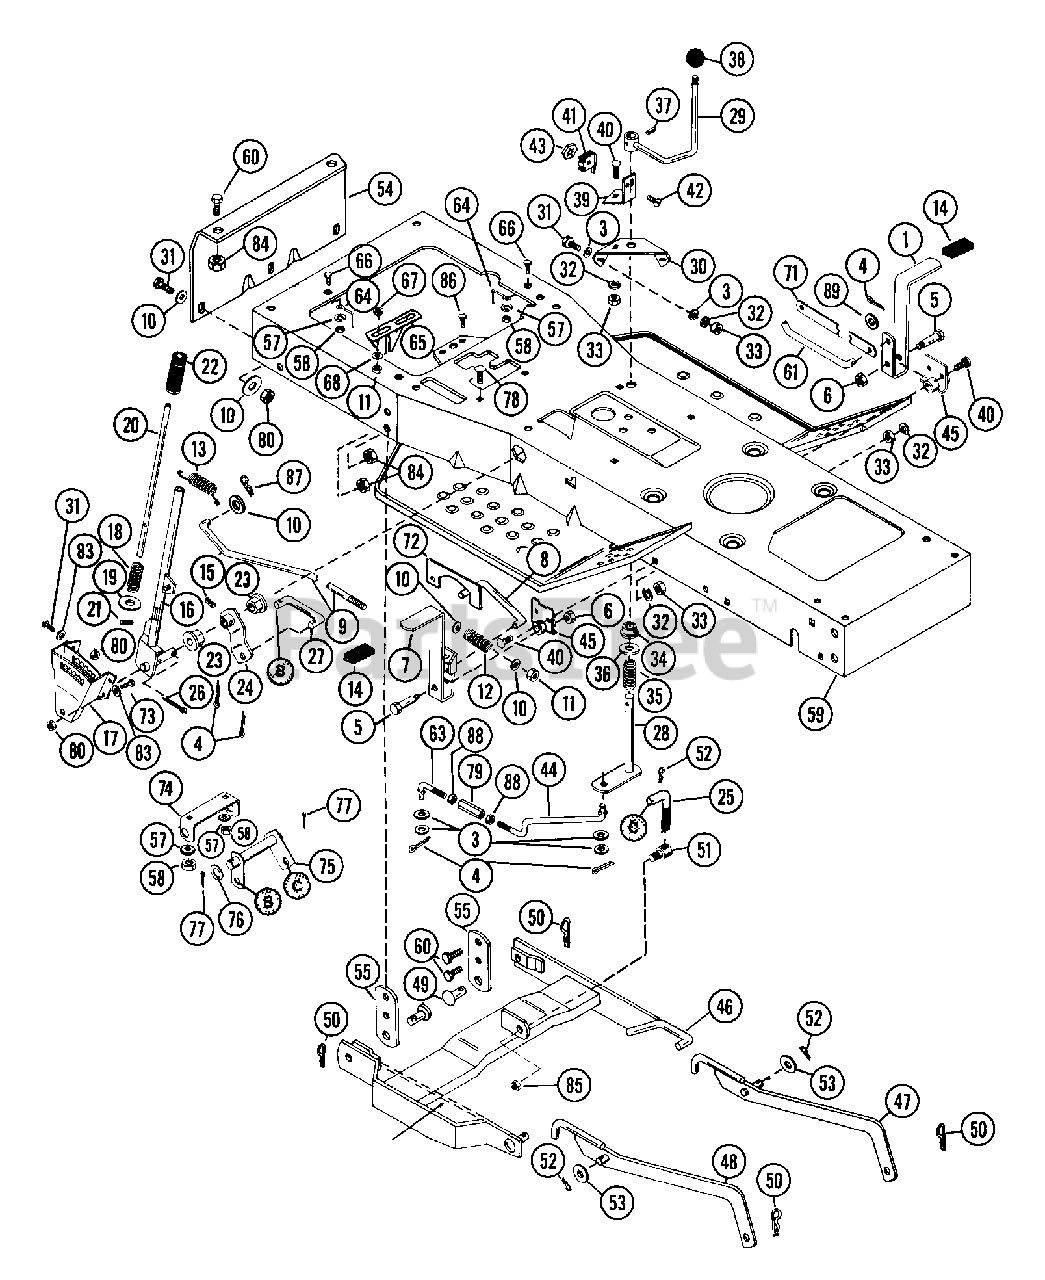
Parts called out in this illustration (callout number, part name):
1	CLUTCH PEDAL
2	NUT-LK-CTR .625-18 PL
3	WSHR-FL-STL.406X.812X.065PL
4	PIN-COTR .12X1.0 PL
5	SHOULDER BOLT .50 X 1.75
6	NUT-LK-JAM-CTR .375-16 PL
7	BRAKE PEDAL
8	PARKING BRAKE ROD
9	BRAKE ROD
10	WSHR-FL-STL .38X.875X.083 PL
11	NUT-LK .312-18 GR A PL
12	SG-COMP .102X.85X1.031
13	SG-TENS .072X.75X2.81 WLD ??
14	PEDAL COVER
15	PIN-GRV .250X1.25 TP A
16	LIFT HANDLE
17	LIFT QUADRANT
18	SG-COMP .048X.59X2.06 WLD9
19	WSHR-FL-STL .458X.750X.06 PL
20	PLUNGER ROD
21	PIN-ROLL .250X1.75
23	FLANGE BUSHING
24	LIFT ARM
25	ADJUSTMENT LINK
26	PIN-COTR .12X1.50 PL
27	LIFT LINK
28	PTO LEVER
29	P T O HANDLE
30	BRACKET
31	BLT-HEX .31-18X.75 PL GR5
32	WSHR-LK .312X.097 PL HVY
33	NUT-HEX .312-18
34	BSHG-FLG.500X.625X.312X.750NY
35	SG-COMP .080X.85X1.44
36	WSHR-FL-STL .531X1.062X.095 PL
37	PIN-ROLL .188X1.25
38	SHIFT BALL
39	SWITCH BRACKET
40	BLT-RDHDSQNK .31-18X.75 GR5 PL
41	SWITCH INTERLOCK
42	SCR-MCH 10-24X1.00 SLRH PL
43	NUT-KEPS 10-24 PL
44	IDLER LINK
45	PEDAL PIVOT
46	REAR HANGER
47	RIGHT HANGER
48	LEFT HANGER
49	PIN-CLEV .494X1.25 YWZC
50	PIN-HAIR INT .09X.188 PL
51	ROD END
52	PIN-HAIR INT .08X.38X1.42 YWZC
53	WSHR-FL-STL .531X1.062X.095 PL
54	DRAW BAR
55	HANGER BRACKET
57	WSHR-LK .375X.094 MED PL
58	NUT-HEX .375-16
59	FRAME W/DECALS
60	BLT-HEX .38-16X.75 PL GR5
61	CLUTCH ROD
63	IDLER ADJUSTOR LINK
64	BELT FINGER
65	CAM ACTUATOR
66	BLT-HEX .38-16X1.00 PL
67	SPACER -FLANGED .325X.498X.318
68	WSHR-FL-STL.312X.734X.065PL
73	BLT-HEX .31-18X1.25 PL GR5
74	CENTER LIFT BRACKET
75	CENTER LIFT LEVER
76	WSHR-FL-STL .754X1.125X.062 PL
77	PIN-COTR .12X1.50 PL
78	BLT-RDHDSQNK .38-16X.75 SHT PL
79	NUT-CUPLG .375-16 PL
80	NUT-LK-TOP .312-18 GR C PL
81	NUT-JAM .50-13 PL
83	WSHR-FL-STL.312X.734X.065PL
84	NUT-LK TOP .375-16 GR C YWZC
85	NUT-LK-CTR .50-13
86	BLT-HEX .31-18X.88 PL GR2
87	PIN-COTR .12X1.50 PL
88	NUT-JAM .375-16 PL
89	WSHR-FL-STL .438X1.0X.083 PL
